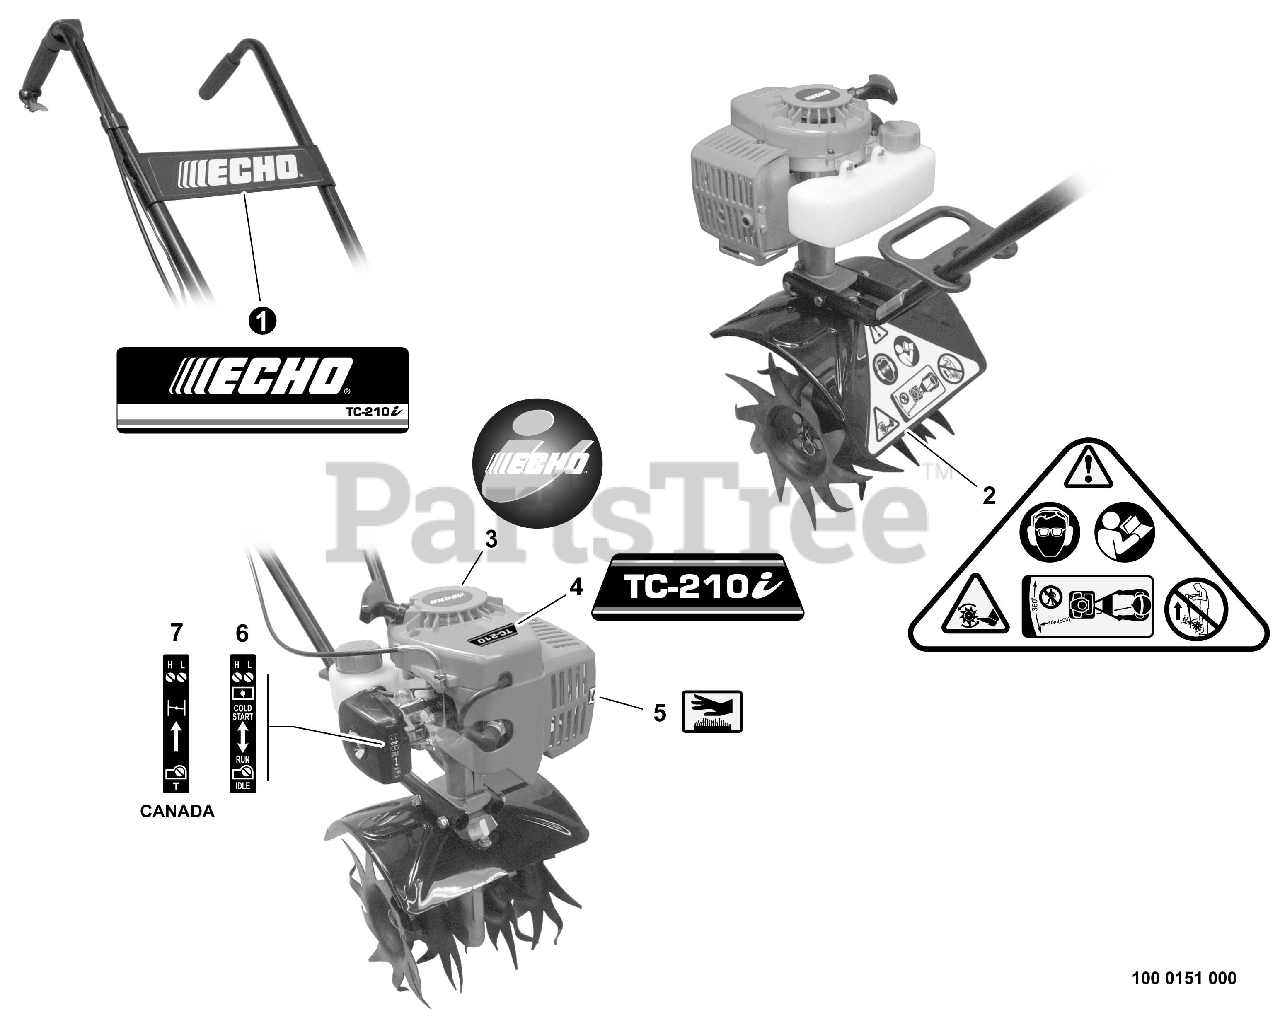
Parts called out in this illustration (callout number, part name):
1	LABEL - MODEL TC-210i
2	LABEL - CAUTION
3	LABEL - ECHO -- i
4	LABEL - MODEL TC-210i
5	LABEL - HOT SURFACE
6	LABEL - CHOKE
7	LABEL - CHOKE
